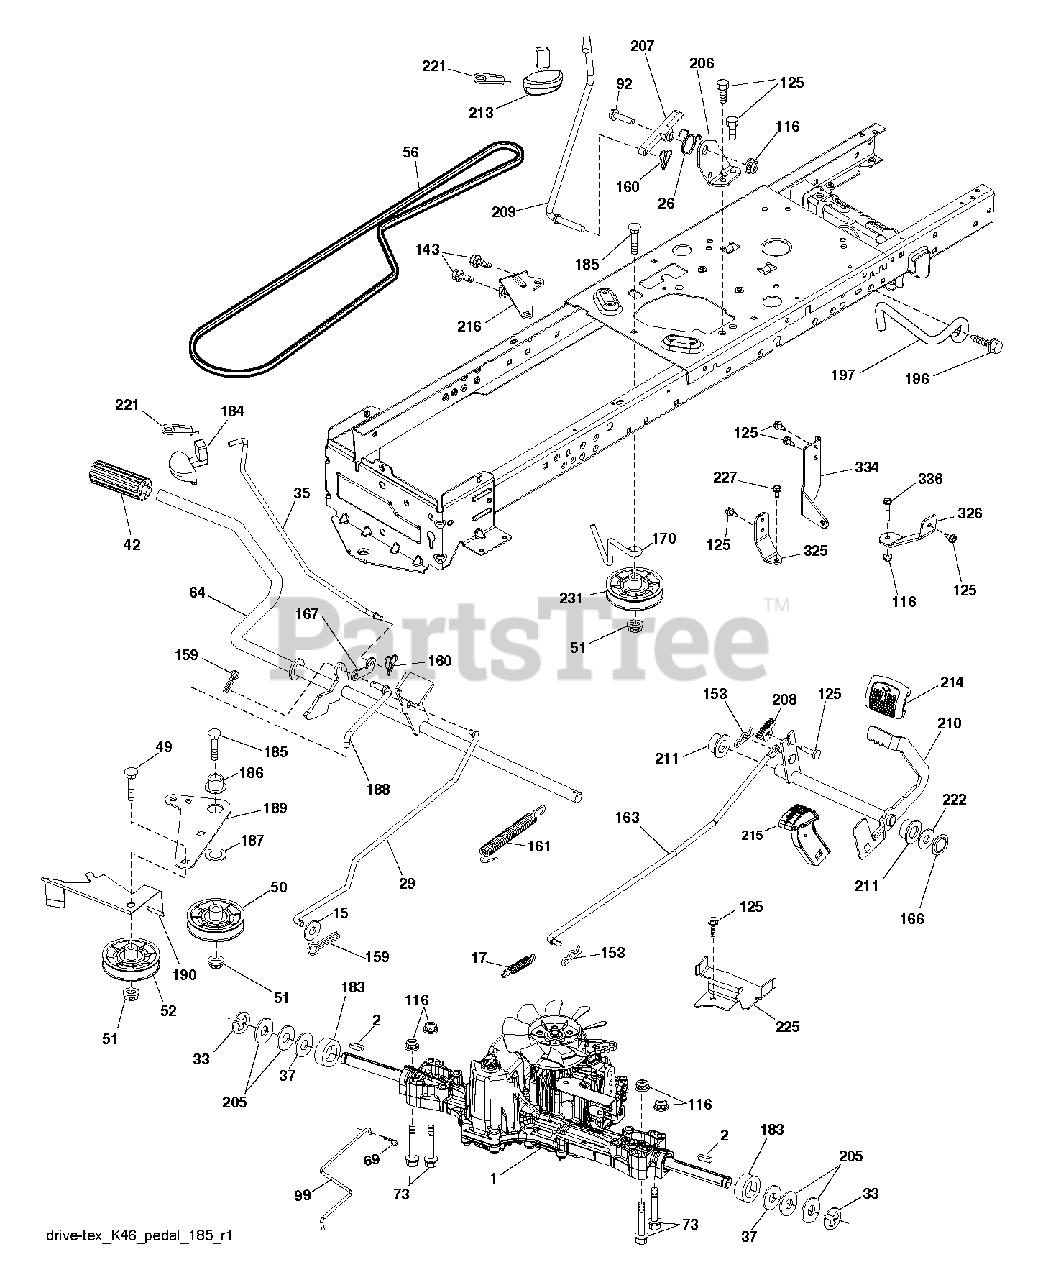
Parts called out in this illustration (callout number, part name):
2	SQUARE KEY
15	WASHER
17	SPRING.BRAKE.K46.GREEN
26	SPRING.RETURN.CRUISE
29	ROD.BRAKE.K46
35	ROD ROD.PARKINGBRAKE.GT.HUSQ/P
37	WASHER.HARDENED
42	PEDAL COVER T
50	IDLER.FLAT.910.OFFSET
51	NUT LOCK FLG 3/8-16 UNC
52	IDLER.V-GROOVE.910.OFFSET
56	V-BELT.MOWER.92.40.42/K46
64	SHAFT.ASM.PEDAL.BRK.CNTR
69	HAIRPIN.SOFT.ZINC.059X1.125
73	BOLT
92	BOLT
99	ARM.PIVOTING.TCRD.GEN2.5.BAGGE
116	NUT LOCK HEX FLANGE 5/16-18
125	SCREW
143	SCR 5/16-18 X 1/2 SELFTAP ZN
153	RETAINER M
159	COTTER PIN
160	RETAINER CLIP
161	SPRING, RETURN LT
163	ROD.CONTROL.K57R.K46
166	NUT.PUSH.625
167	LATCH.BRAKE.SPRING
170	KEEPER.CENTER SPAN.1.688
183	SPACER AXLE
184	HANDLE.PARKING.BRAKE.H (BLK)
186	SPACER.RETAINER
187	WASHER 12/32X2X10GA
188	LINK.CLUTCH.GROUND DRIVE.LONG
189	BELLCRANK.GROUND.DRIVE.TEX.
190	KEEPER.BELLCRANK.DRIVE
196	SCREW 3/8-16X1
197	CLUTCH.ANTIROTATION.WIREFORM.
206	BRACKET.MOUNT.CRUISE.LATCH
207	LATCH.CONTROL.CRUISE.TEX
208	GEAR.SECTOR.CONTROL.CR
209	ROD ROD.CRUISECONTROL.GT.HUSQ/
210	ROCKER.ASM.PEDAL.CONTR
211	BEARING.NYLON
213	KNOB.CONTROL.CRUSIE.HU
214	PEDAL.FORWARD.PAD.TEX
215	PEDAL.COVER.REVERSE.CRD.X428BK
216	BRACKET.PULLEY.IDLER.W/TEX
221	RETAINER.SPRING.CLIP.H
222	WASHER 21/32 X 1-1/4 X 10 GA.
225	KEEPER.BELT.TRANSAXLE.K46
227	SCREW
231	IDLER.V-GROOVE.1.688.OFFSET
325	BRCKT.PNT.TRQ.STP.46.18TIRE.RH
326	TORQUE.STRAP.K46.LT.LH
334	SWAY.ROD.BRACKET.K46.X431
336	BOLT.5/16-18X1-3/4.FLANGED.HEX
